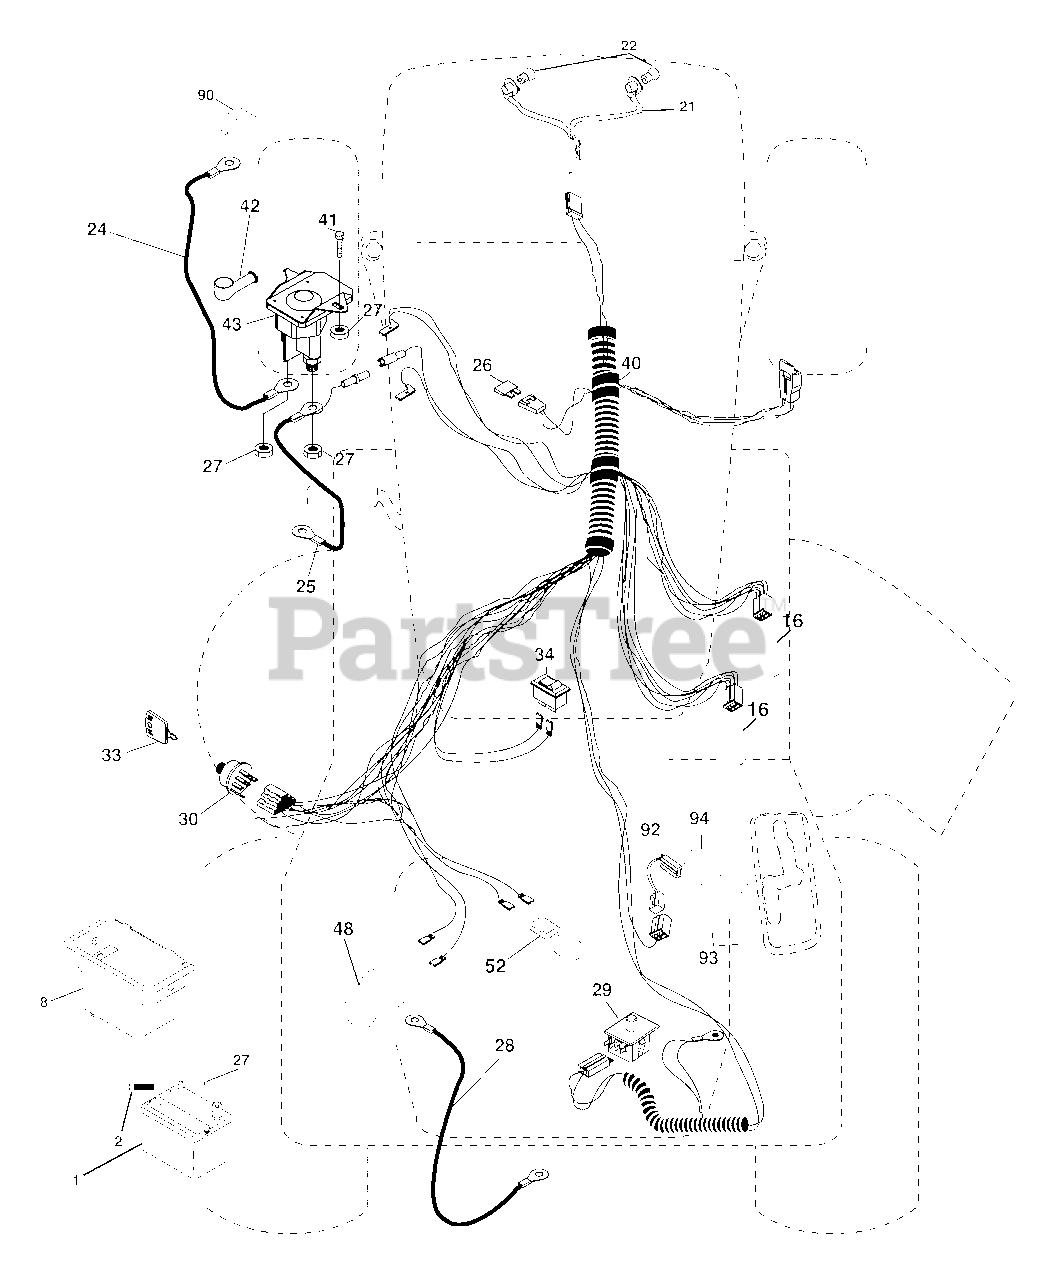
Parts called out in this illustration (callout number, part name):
1	Battery
2	Bolt Hex Hd 1/4-20 unc x 3/4
8	Box Battery
16	Switch Interlock
21	Harness Socket Light
22	Bulb, Light # 1156
24	Cable Battery
25	Cable Battery 6 Ga. Red w/16 wire 44"
26	Fuse
27	Nut Keps Hex 1/4-20 unc
28	Cable Ground 12" Blk 6 Ga.
29	Switch Seat
30	Switch Ign
33	Key Ign Molded Generic
34	Switch Light/Reset
40	Harness Ign
41	Bolt Fin Hex 1/4-20 unc x 1/2
42	Cover Terminal Red
43	Solenoid
48	Adapter Ammeter
52	Protection Loop
90	Cover Terminal
92	Harness Pigtail Reverse Switch
93	Screw Plastite 10-14 x 2.0
94	Module Reverse ROS
